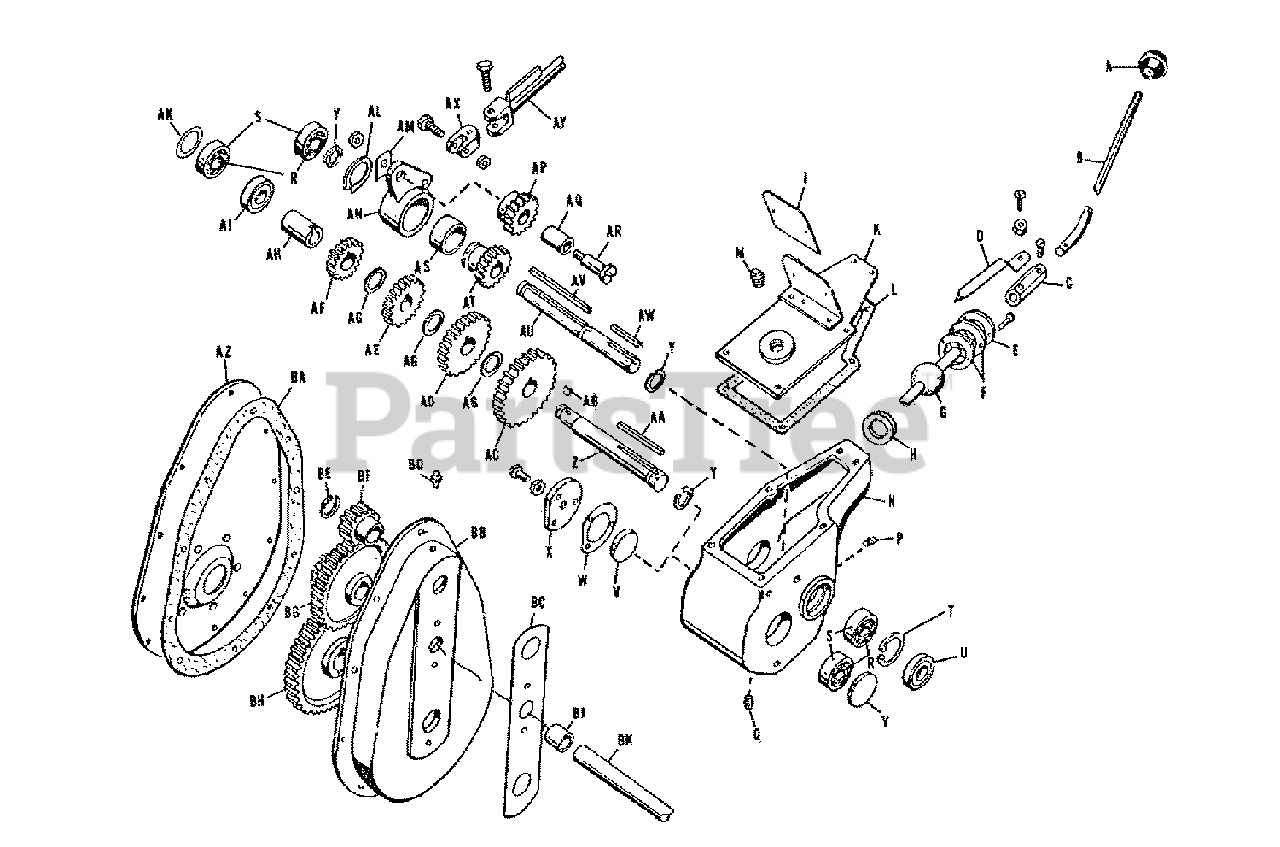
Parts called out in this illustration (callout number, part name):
A	BALL, Shift Lever
B	EXTENSION, Gear Shift Handle
C	COUPLING, Gear Shift Handle
D	POINTER, Shifter
E	RETAINER, Gear Shift Ball
F	SPACER, Shift Ball
G	BALL, Gear Shift
H	WASHER, Shift Ball
I	PLATE, Serial and Shift - VC only
J	PLATE, Serial, and Shift - H only
K	COVER ASSEMBLY, Transmission Gear Case
L	GASKET, Transmission Gear Case Cover
M	PLUG, Filler
N	CASE, Transmission Gear
P	PLUG, Pipe, 1/8 Standard Square Head
Q	PLUG, Pipe, 1/4 Standard Square Head
R	CONE, Roller Bearing
S	CUP, Roller Bearing
T	RING, Retaining
U	SEAL, Oil
V	PLATE, Transmission Bearing Take-Up
W	GASKET, Adjusting Plate
X	PLATE, Tranmission Bearing Adjustment
Y	RING, Retaining
Z	SHAFT, Transmission Pinion
AA	KEY, Transmission Pinion Shaft
AB	KEY, Woodruff 5/32 x 5/8
AC	GEAR, "Reverse"
AD	GEAR, "Low"
AE	GEAR, "Medium"
AF	GEAR, "High"
AG	SPACER, Tranmission Gear
AH	SPACER, Transmission Pinion Shaft
AJ	SEAL, Oil
AK	SHIM, Transmission Bearing Cup (Either/Or - 1 or 2 as required)
AL	RING, Retaining
AM	PLATE, Lock
AN	ARM, Tranmission Rocker w/bearing
AP	PINON, Rocker Arm w/bearing
AR	PIN, Rocker Arm Pinion
AS	BEARING, Rocker Arm
AT	GEAR, Tranmission Slide
AU	SHAFT, Tranmission Pulley
AV	KEY, Transmission Pulley Shaft
AW	KEY, Transmission Pulley
AX	PITMAN, Gear Shift
AY	CLEVIS ASSEMBLY, Pitman
AZ	COVER ASSEMBLY, Gear Case
BA	GASKET, Gear Case Cover
BB	CASE, Gear
BC	GASKET, Gear Case
BD	FITTING, Grease, Alemite #1641
BE	RING, Retaining
BF	PINION, Reduction
BG	GEAR ASSEMBLY, Cluster
BH	GEAR, Drive
BJ	BEARING, Intermediate Pinion
BK	SHAFT, Intermediate
